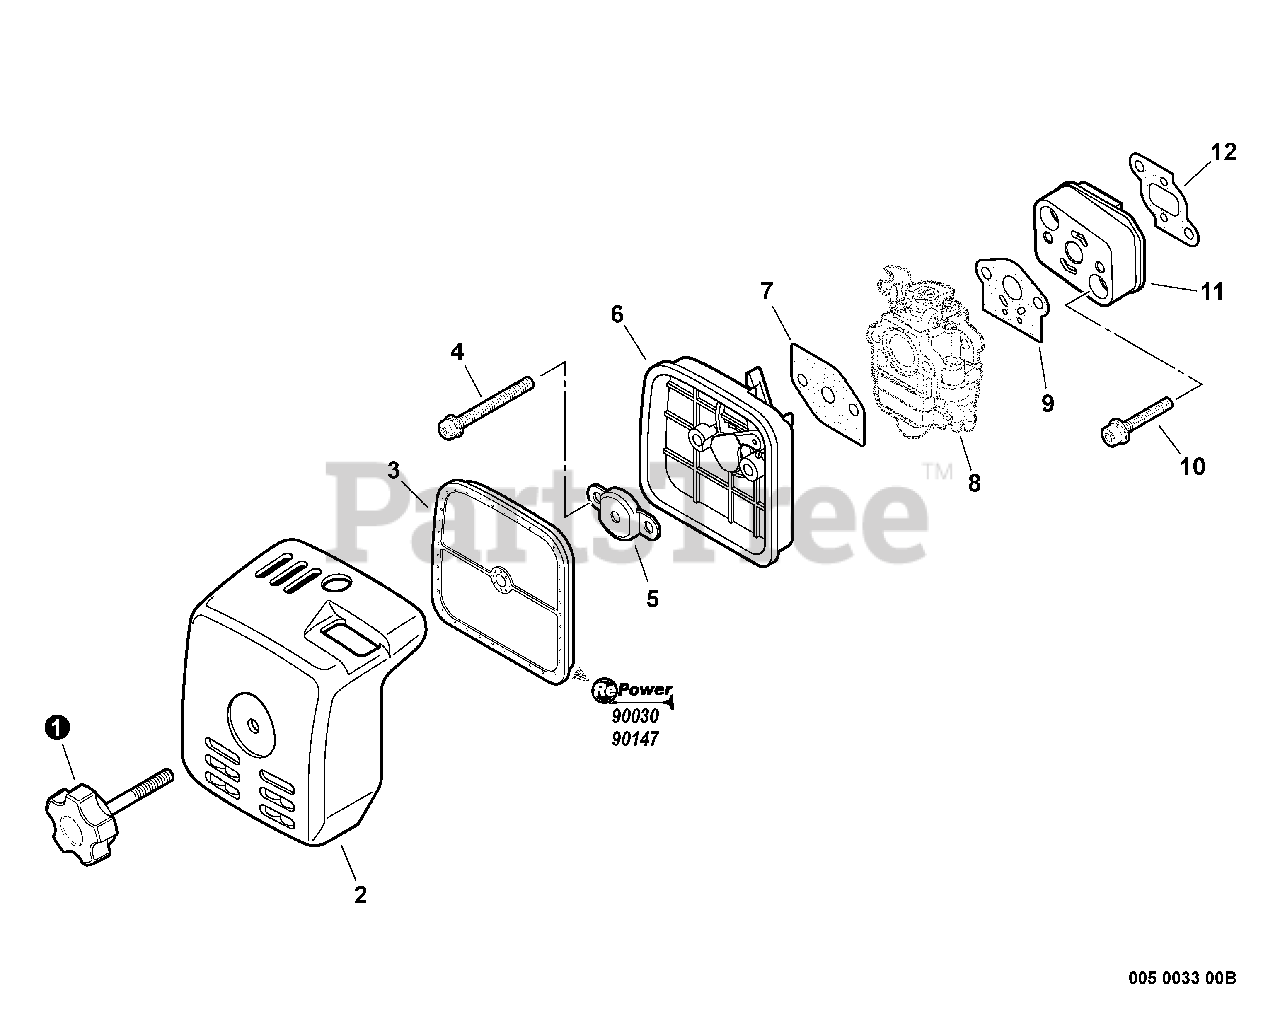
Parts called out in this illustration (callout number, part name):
1	THUMBSCREW
2	COVER, AIR FILTER
3	FILTER, HEAVY-DUTY AIR
4	SCREW 5×60
5	PLATE, PREVENT
6	CASE, AIR FILTER
7	GASKET, INTAKE
8	CARBURETOR
9	GASKET, CARBURETOR
10	BOLT 5×25
11	INSULATOR, INTAKE
12	GASKET, INTAKE
13	REPOWER FILTRATION KIT
14	TUNE-UP KIT
